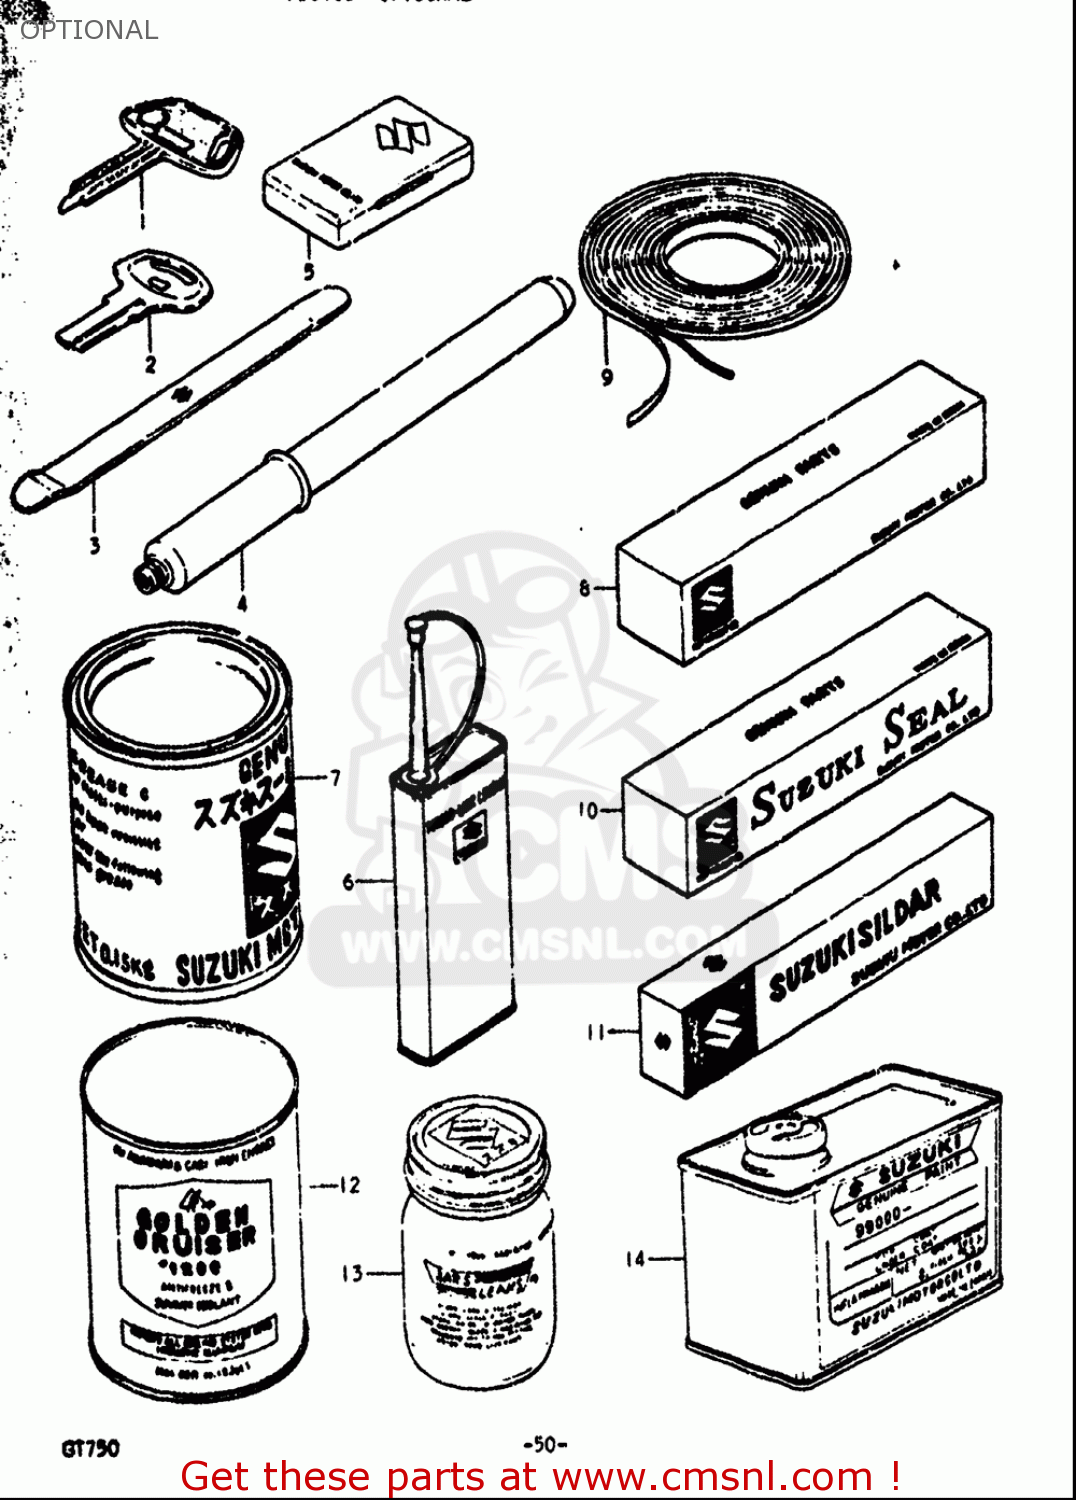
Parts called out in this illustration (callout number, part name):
2	KEY,BLANK
3	LEVER,TIRE
6	THREAD LOCK NO.1401 CLEAR 200G
7	GREASE(C)EP2 LITHIUM 150G
8	BOND 1104
13	LEAK END 0.4GX70
